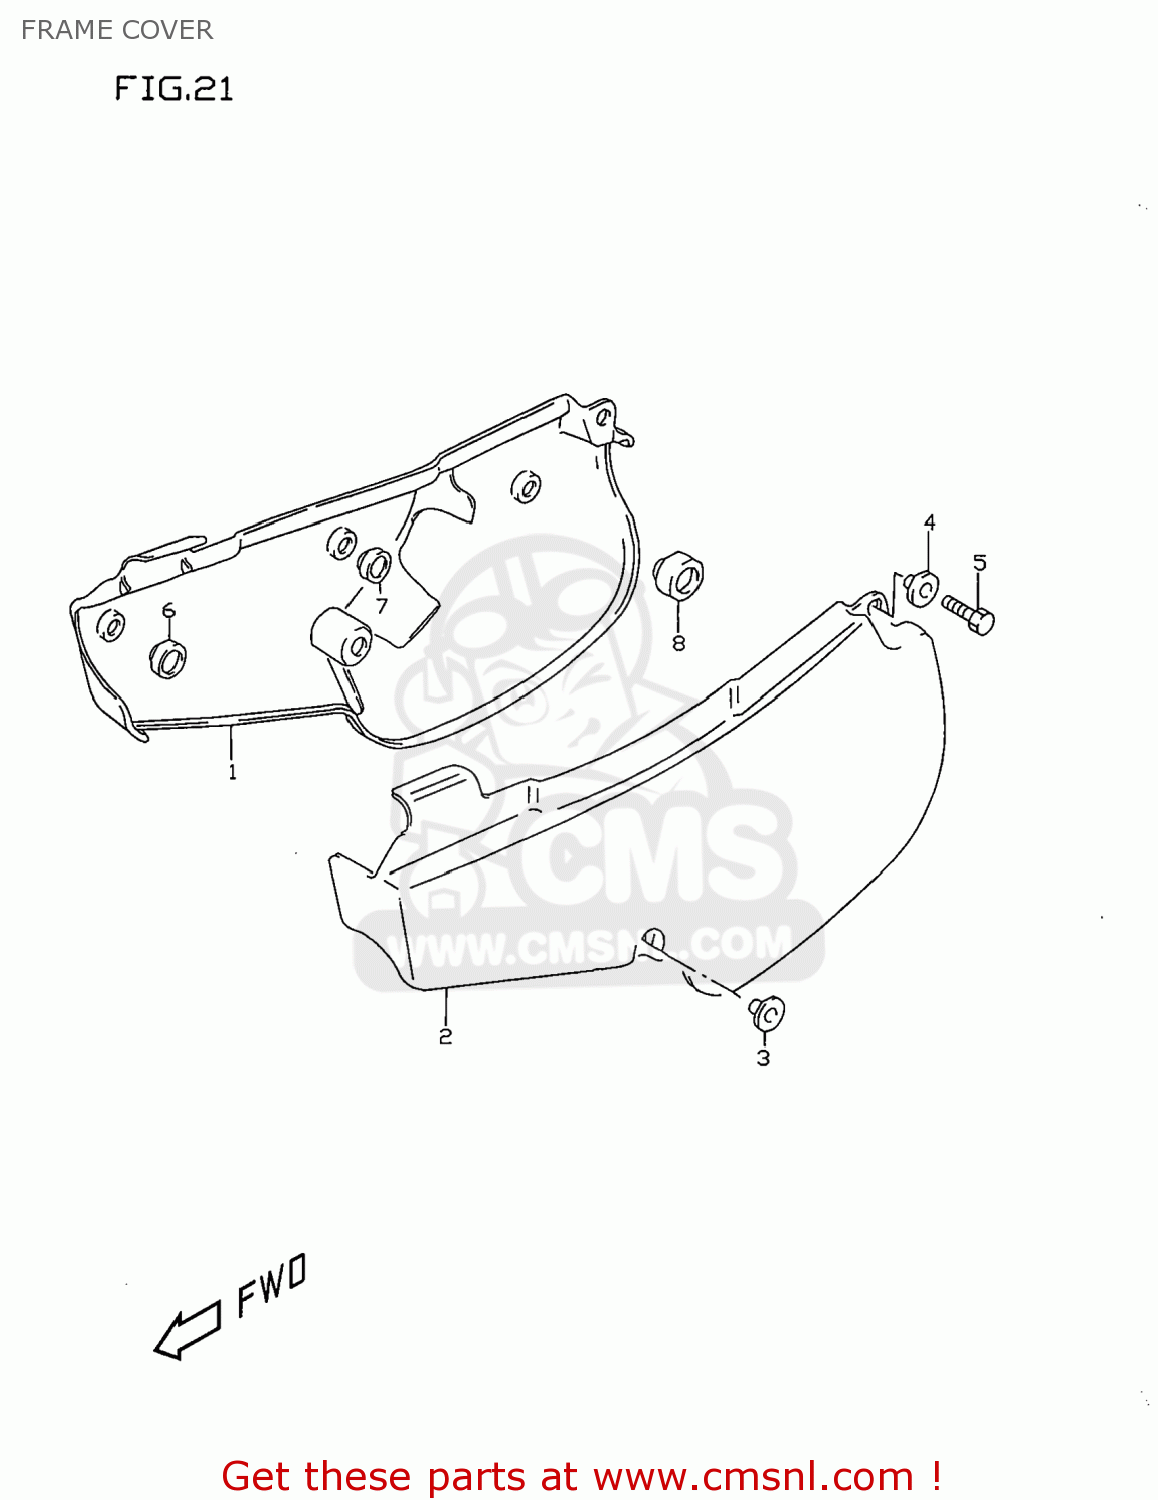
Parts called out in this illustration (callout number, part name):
1	COVER,SIDE,R(WHITE)
2	COVER,SIDE,L(WHITE)
3	WASHER
4	WASHER
5	SCREW
6	CUSHION
7	CUSHION
8	CUSHION
